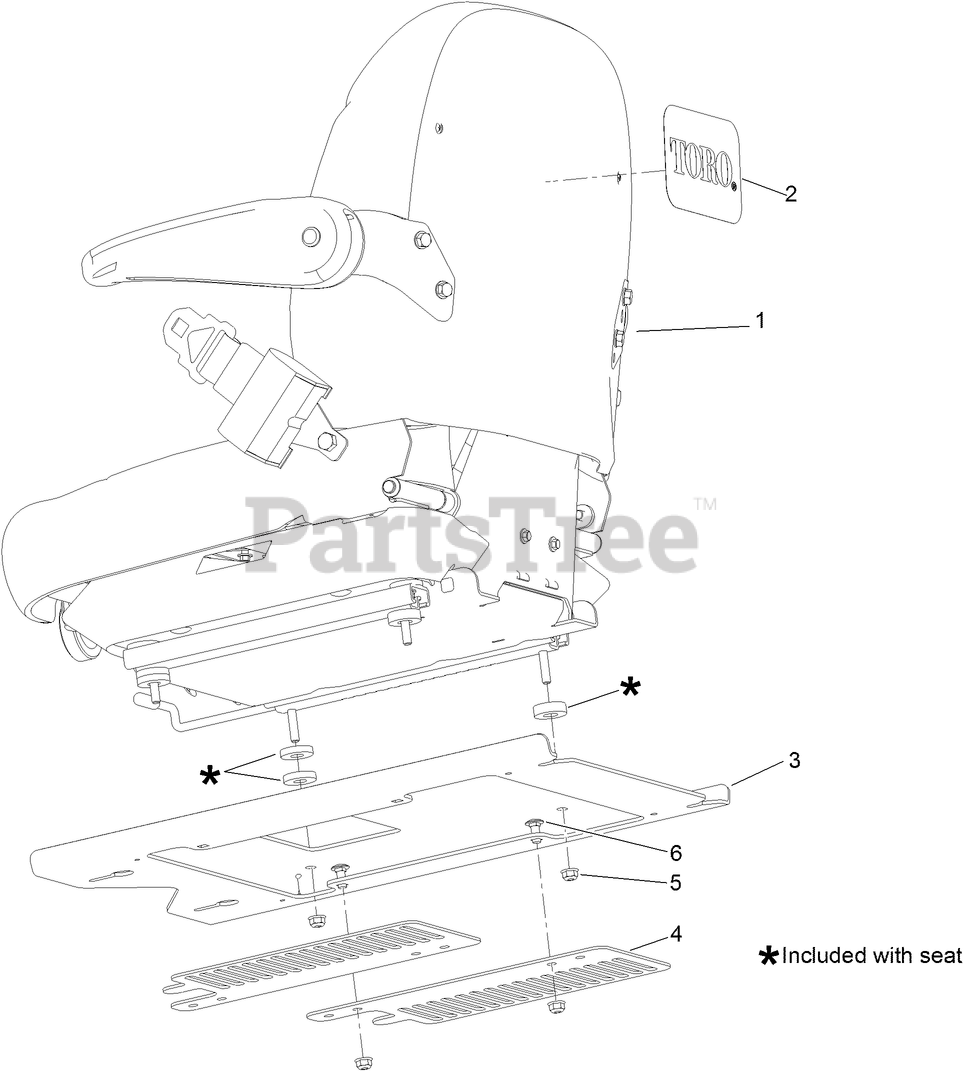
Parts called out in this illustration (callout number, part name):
1	SUSPENSION SEAT ASM
2	DECAL
3	SEAT MOUNT BRACKET ASM
4	PLATE-COVER, FAN
5	NUT-HF, NI
6	SCREW-CARR
